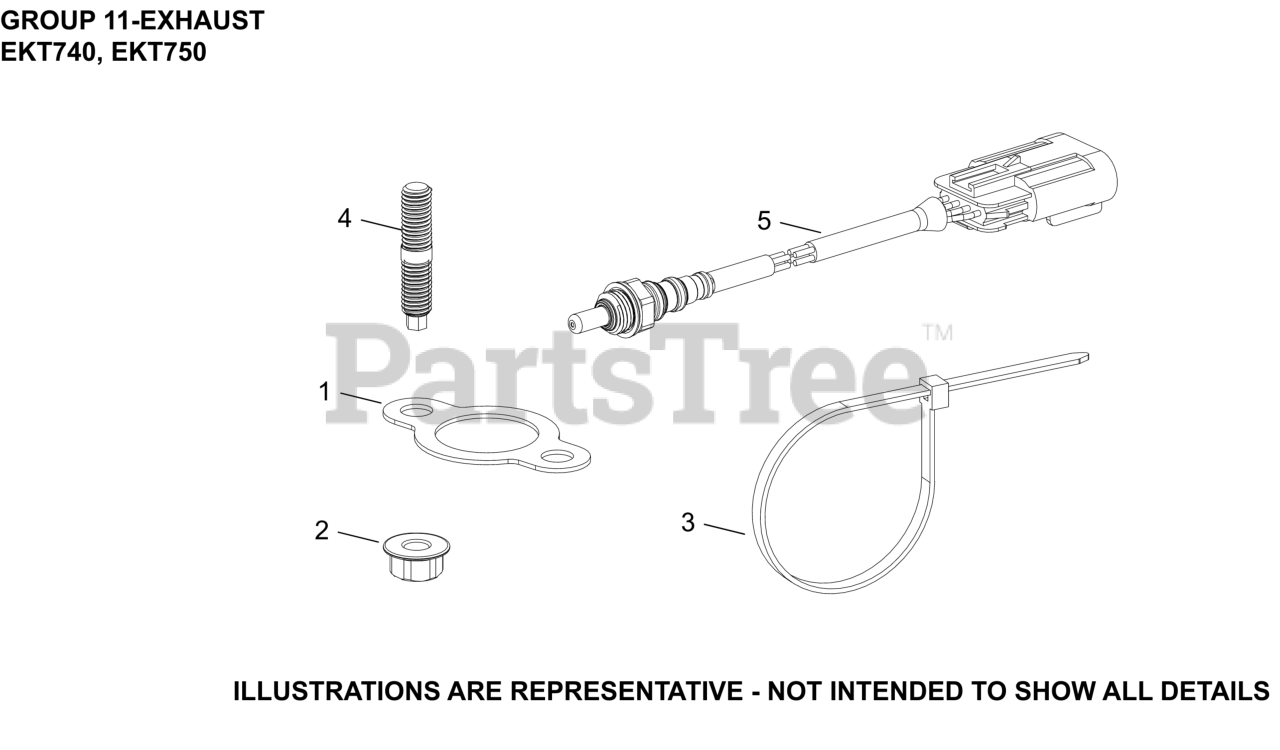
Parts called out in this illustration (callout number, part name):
2	NUT, HEX FLANGE LOCK (M8)
NI	STUD, METRIC EXHAUST
NI	SENSOR, OXYGEN (M12 x 1.25 THREADS)
